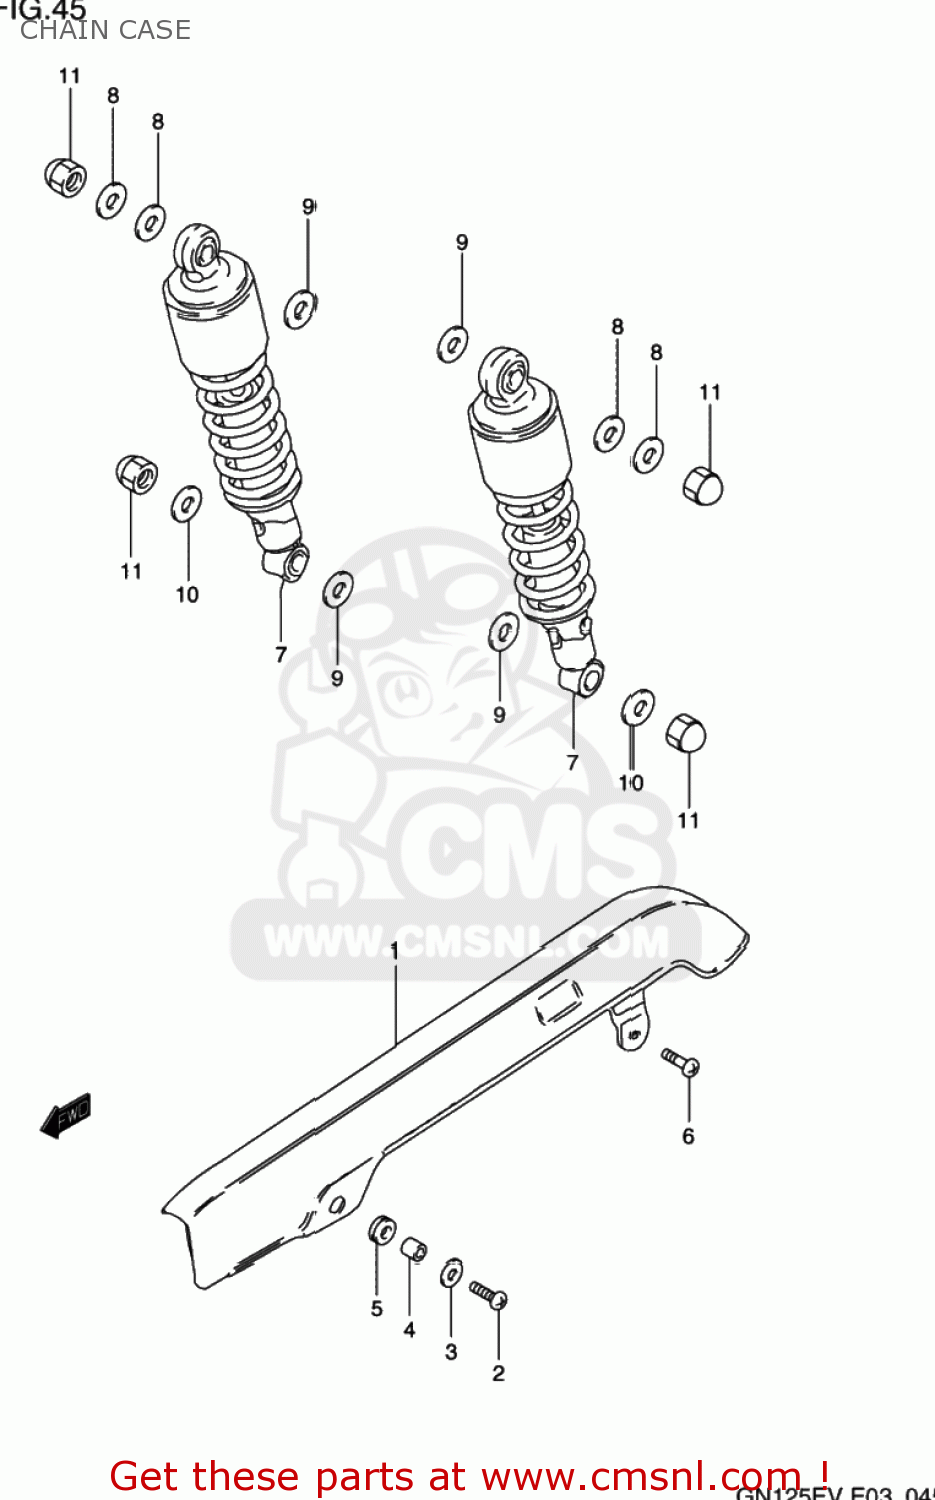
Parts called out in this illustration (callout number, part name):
1	CASE,CHAIN
2	SCREW
3	WASHER(6.5X20X1.2)
4	SPACER(6.5X9X7)
5	CUSHION
6	SCREW
7	ABSORBER ASSY,RR SHOCK
8	WASHER (10.5X24X2.3)
9	WASHER (12.5X26X1.6)
10	WASHER (10.5X24X2.3)
11	NUT
